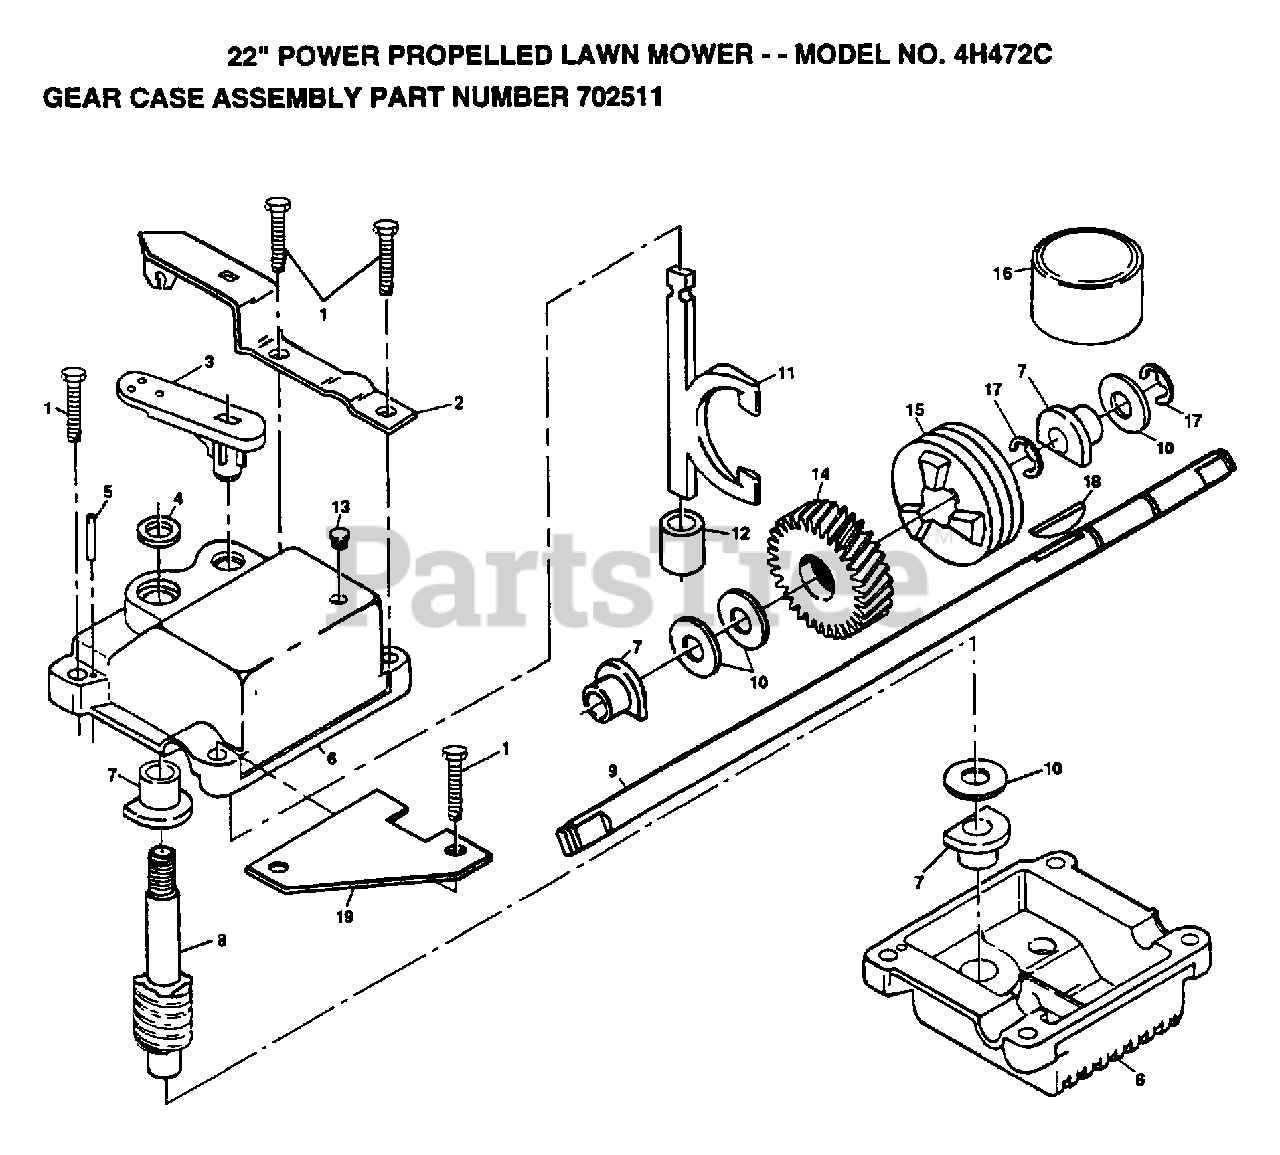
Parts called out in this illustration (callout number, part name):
1	SCREW.1/4-20
2	BRACKET.GEARCASE
3	SHIFTER
4	SEAL
5	PIN GROOVED 1/8X5
6	KIT GEARCASE HALV
7	BEARING
8	SHAFT.WORM
9	SHAFT.DRIVE
10	THRUST WASHER
11	CLUTCH YOKE
12	BUSHING.GEAR BOX
13	PLUG PM
14	GEAR.HELICAL
15	CLUTCH JAW
17	RING T
18	HI PRO KEY
